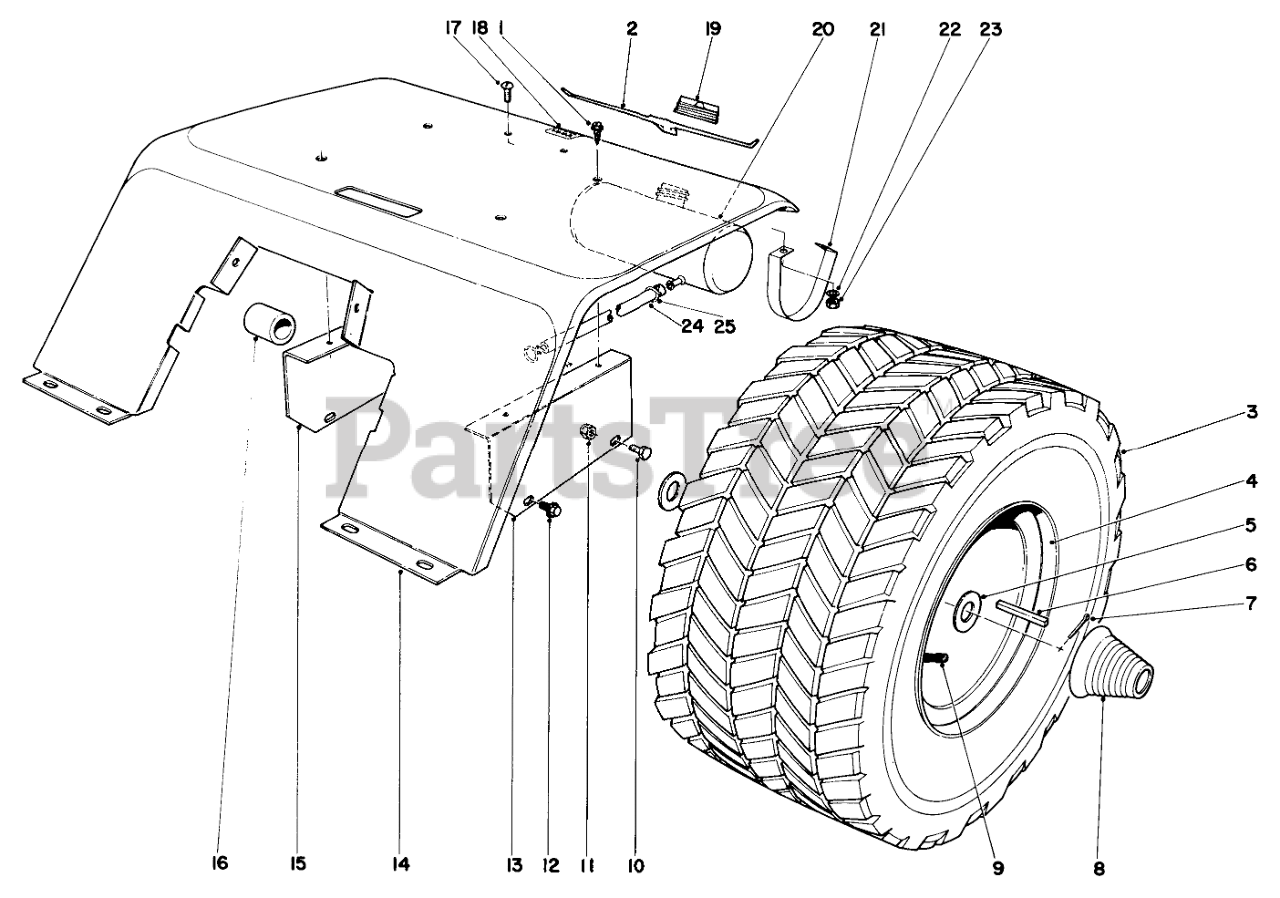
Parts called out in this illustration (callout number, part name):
1	10-16 X 3/8 THDG SCREW
2	Decal
5	Washer
6	KEY-CLUTCH
7	PIN-COTTER
8	Hub Cap
9	VALVE -STEM
10	SCREW-HH
11	Nut
13	Fender Support L.H.
14	Fender
15	Fender Support R.H.
16	Spacer
18	Decal, Oil
20	Tank, Oil Reservoir
21	Strap
22	WASHER-LOCK
23	NUT-HEX
25	Clamp
